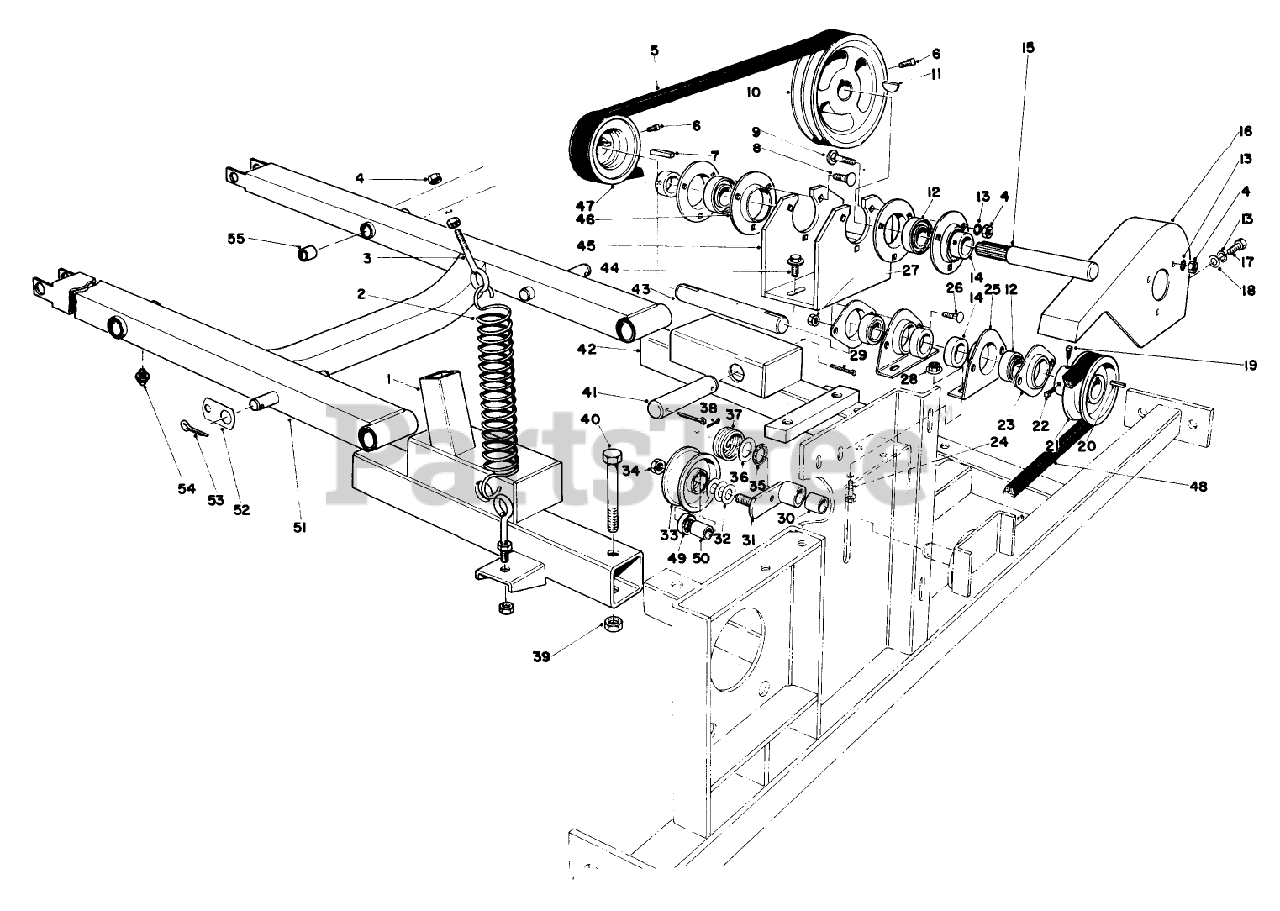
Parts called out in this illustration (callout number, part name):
1	Adapter R.H.
2	Extension Spring
3	Eyebolt
4	NUT-HEX
5	V-BELT
6	SCREW-SET, SQH
8	SCREW-CARR
9	Bolt-Carriage
10	JACKSHAFT PULLEY
11	KEY-WOODRUFF
12	Bearing (Incl.Ref.#14)
13	WASHER-LOCK/SP
14	COLLAR-LOCK, BEARING
15	JACKSHAFT
16	Belt Shield
17	SCREW-HH
18	WASHER-PLAIN
19	5/16-18 X 1/2 SQ HD
21	SHEAVE 60103
22	SCREW-SQH
23	Flange
24	Capscrew
25	FLANGE
26	BOLT-CARR
27	NUT-HF
28	NUT-HHF, WHIZ
29	3/32 X 1-3/4 LG COTTER
30	BUSHING 16162
31	Idler Arm (Incl.Ref.#30)
32	WASHER-FLAT
33	Idler Pulley
34	LOCKNUT 6239
35	Felt Washer
36	Washer
37	Spring-Torsion
38	PIN-COTTER
39	NUT-LOCK, CONE
40	SCREW-HH
42	Adapter L.H.
43	JACKSHAFT
44	SCREW-HHF
45	JACKSHAFT SUPPORT
46	FLANGE
47	JACKSHAFT PULLEY
48	V-BELT
49	Bearing
50	Sleeve
51	Lift Arm (Incl.Ref.#53 & 54)
52	BRAKE SPRNG STRAP R
53	PIN-COTTER
54	GREASE FITTING
55	7/8 ID X 1.128 X 7/8 LG BSHG
